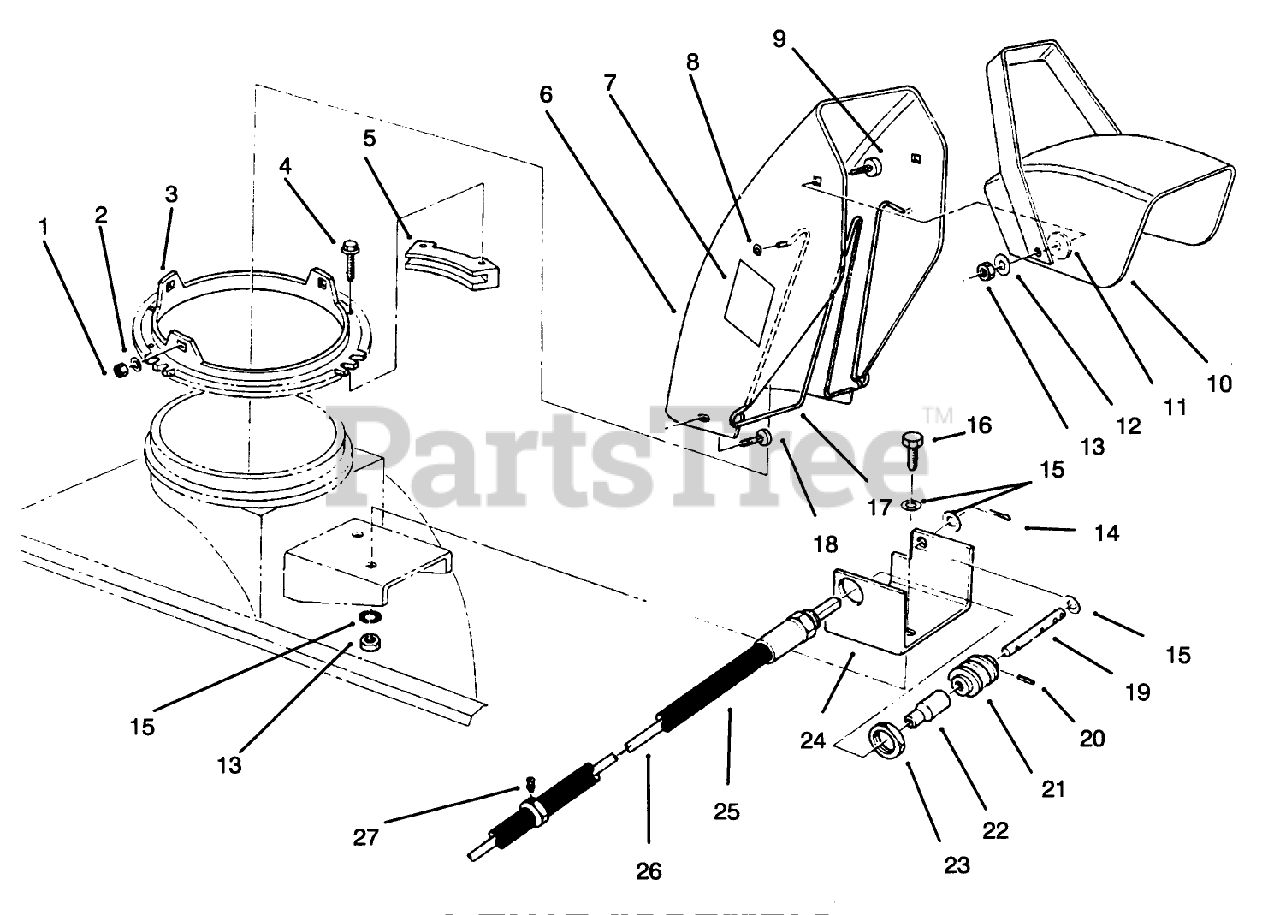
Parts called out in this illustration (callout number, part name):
1	NUT-LOCK, NI
2	WASHER-PLAIN
3	Screw
4	SCREW-SPECIAL
5	RETAINER-CHUTE
6	Chute-Upper (Incl. Ref. # 7)
7	NIPPLE
8	NUT-PUSH
9	BOLT-CARR
10	Deflector
11	WASHER-RUBBER
12	WASHER-BELLEVILLE
13	NUT-LOCK, NI
14	PIN-COTTER
15	WASHER-FLAT
16	SCREW-HH
17	CHUTE WIRE
18	SCREW-CARR
19	SHAFT-GEAR, WORM
20	PIN-SPRING
21	GEAR-WORM, CHUTE
22	COUPLER
23	LOCKNUT
24	WORM GEAR BRKT R
25	HOSE ASM
26	FLEX SHAFT
27	FITTING-GREASE
